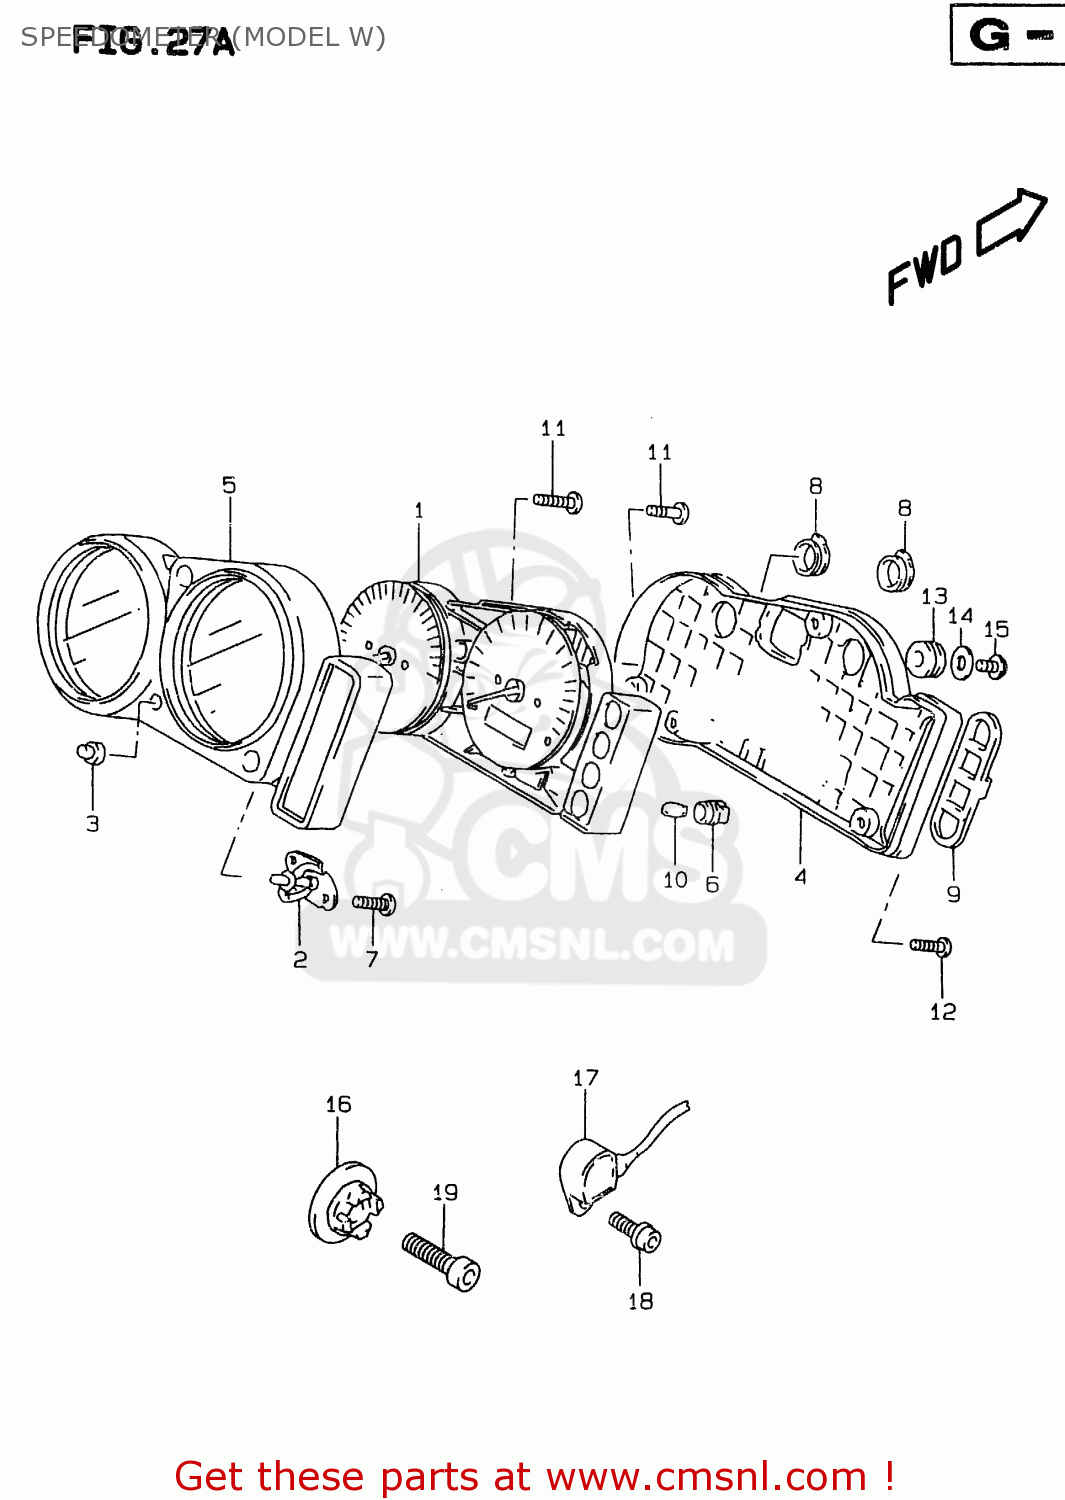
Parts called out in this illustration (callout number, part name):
1	SPEEDOMETER (MILE/KILO)
2	ATTACHMENT,SWITCH
3	SWITCH,GUM
4	CASE ASSY
5	VISOR,METER
6	SOCKET
7	SCREW(3X10)
8	CAP,BLIND NO.1
9	CAP,BLIND NO.2
10	BULB(12V1.7W,T6.5)
11	SCREW
12	SCREW
13	CUSHION,METER
14	WASHER(5.5X16X1.2)
15	SCREW
16	ROTOR,SPEED
17	SENSOR,SPEED
18	BOLT
19	BOLT
